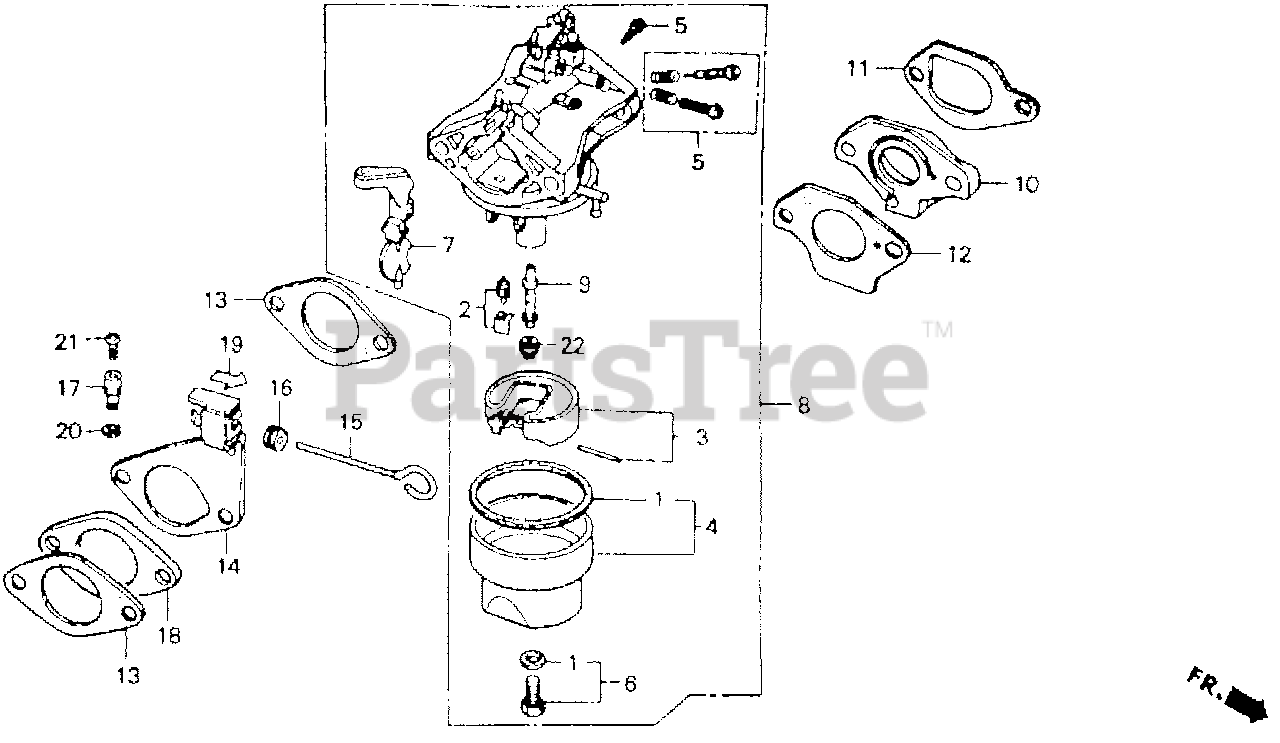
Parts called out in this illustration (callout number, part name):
1	GASKET SET
2	VALVE SET, FLOAT
3	FLOAT SET
4	CHAMBER SET, FLOAT
5	SCREW SET A
6	SCREW SET B
7	CHOKE SET
8	CARBURETOR ASSY.
8	CARBURETOR ASSY. (BB35D E)
9	NOZZLE, MAIN
10	INSULATOR, CARBURETOR
11	GASKET, INSULATOR
12	GASKET, CARBURETOR
13	GASKET, AIR CLEANER
14	STAY, CHOKE CONTROL
15	ROD, CHOKE CONTROL
16	GROMMET, CHOKE ROD
17	HOLDER, CABLE
18	SPACER, AIR CLEANER
19	MARK, CHOKE
20	CIRCLIP (5MM)
21	SCREW, PAN (4X8)
22	JET, MAIN (#88)
22	JET, MAIN (#90)
22	JET, MAIN (#92)
22	JET, MAIN (#95)
22	JET, MAIN (#98)
22	JET, MAIN (#100)
22	JET, MAIN (#102)
